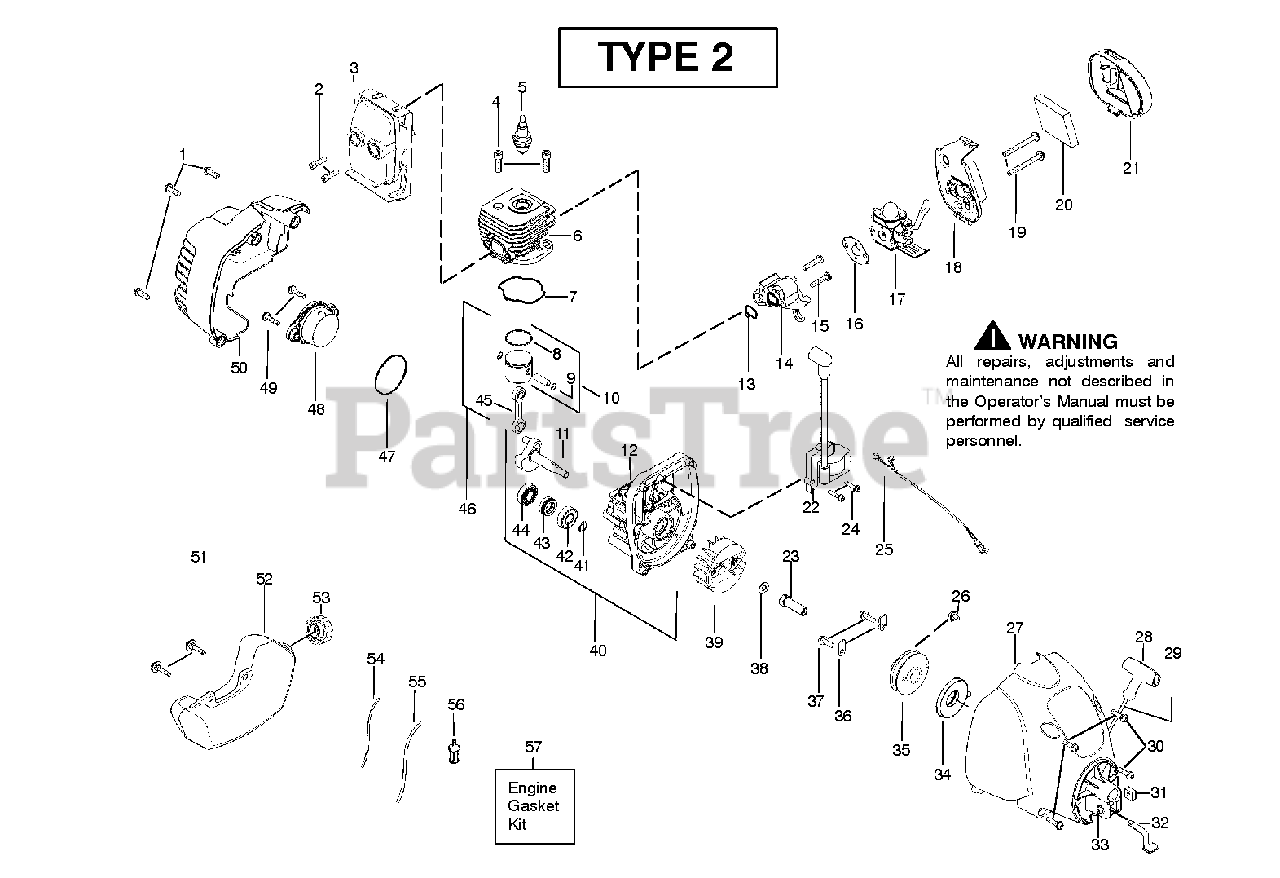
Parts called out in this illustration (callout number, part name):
2	BOLT MUFFLER
3	ASSEMBLY
5	PLUG-SPARK (RCJ-6Y)
6	CYLINDER MACHINED 25CC LO
7	KIT GASKET 25CC
8	PISTON RING
9	WRIST PIN RET.
10	PISTON KIT
11	ASSY CRANKSHAFT
12	ASSY CRANKCASE
13	KIT GASKET 25CC
14	ADAPTOR CARBURETOR
16	KIT GASKET 25CC
17	KIT CARB ASSY #C1U-W18
18	BASE AIRBOX
20	FOAM AIR FILTER
21	COVER AIR BOX
23	DRIVE-COUPLING
25	CABLE ASSY
26	SCREW SEMS TOOTHED WASHER
28	HANDLE-STARTER
29	KIT ROPE
31	NUT SQUARE
34	STARTER SPRING
35	STARTER PULLEY KIT
36	RETAINER
37	SCREW 8-16 X 9/16 (PLAS
38	WASHER FLAT
39	ASSY FLYWHEEL
40	ASSEMBLY
41	RETAINING RING
42	OUTER BEARING
44	BEARING
45	KIT-CONN ROD ASSY
46	PISTON KIT
47	KIT GASKET 25CC
48	ASSY REAR PLUG
50	CYLINDER COVER
51	SCREW FUEL TANK RETAINER
52	ASSY FUEL TANK
53	CAP ASSY W/ RETAINER
54	KIT-LINE
55	LINE KIT
56	FUEL PICK-UP ASSY
57	KIT GASKET 25CC
